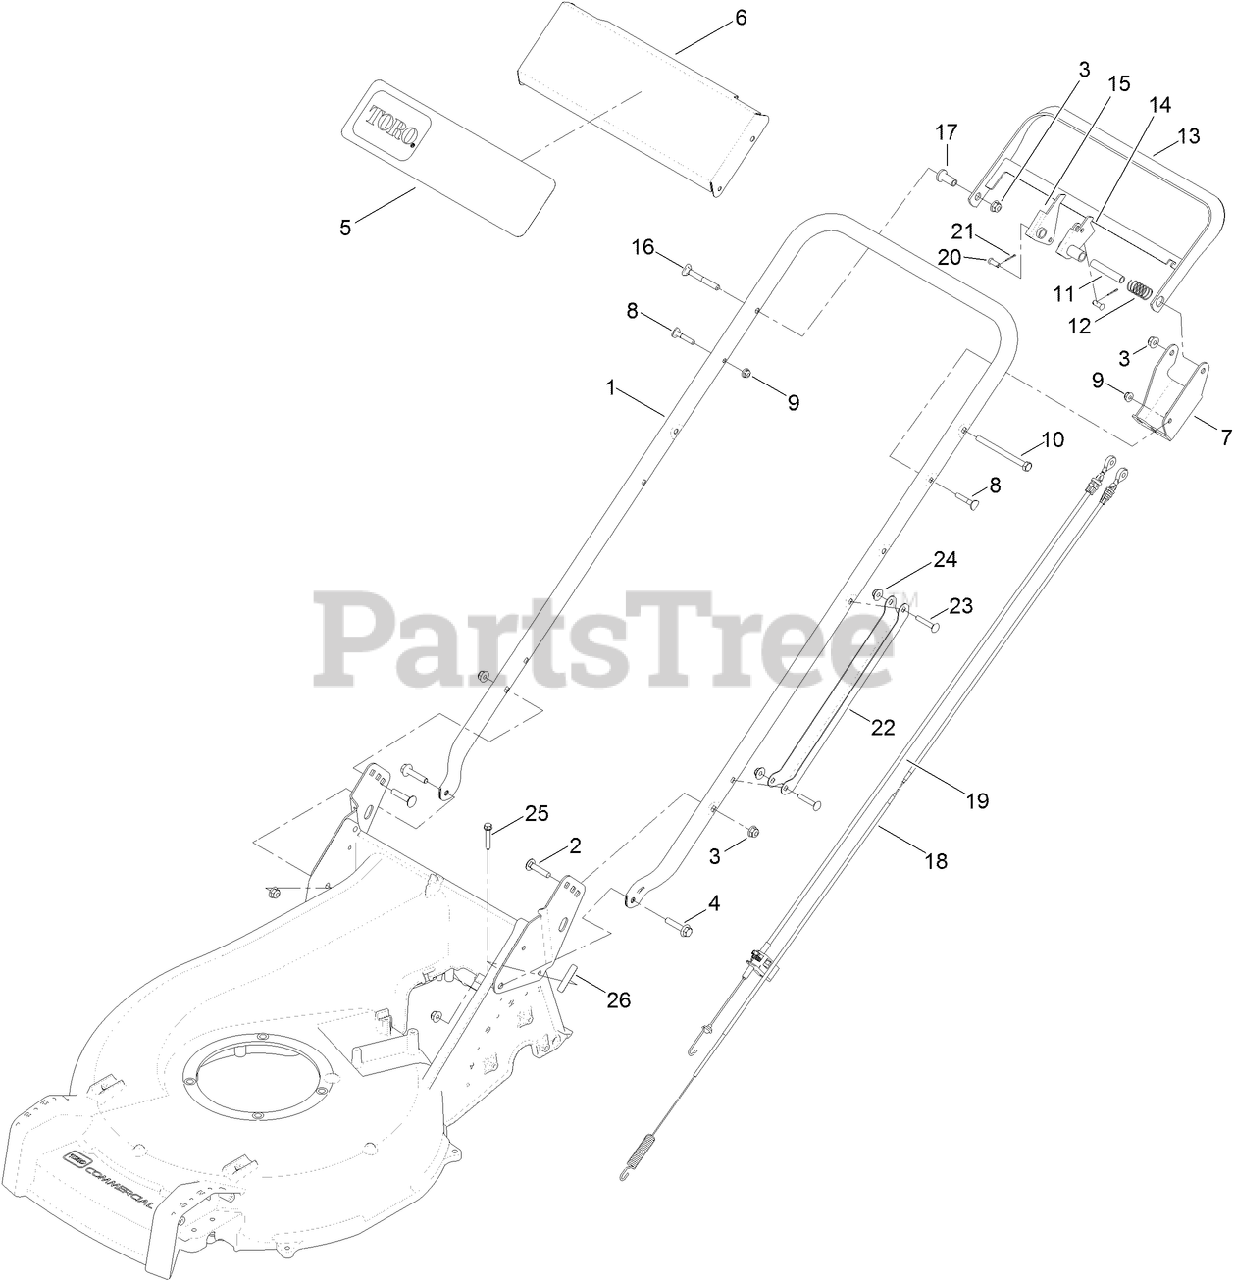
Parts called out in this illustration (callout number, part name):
1	HANDLE
2	BOLT-CARR
3	NUT-HF, NI
4	SCREW-HHF
5	DECAL-TORO, PROLINE
6	PANEL-CONTROL
7	BRACKET-CONTROL
8	SCREW-HANDLE
9	NUT-HF
10	SCREW-HH
11	SPACER
12	SPRING-CONTROL
13	BAR-CONTROL
14	LEVER-CONTROL
15	LEVER-TRACTION
16	SCREW-HANDLE
17	SPACER-FLANGE
18	CABLE-BBC
19	CABLE-TRACTION, BBC
20	PIN-CABLE
21	PIN-COTTER
22	GUARD-CABLE, HANDLE
23	SCREW-CARR
24	NUT-HF
25	SCREW-HWH
